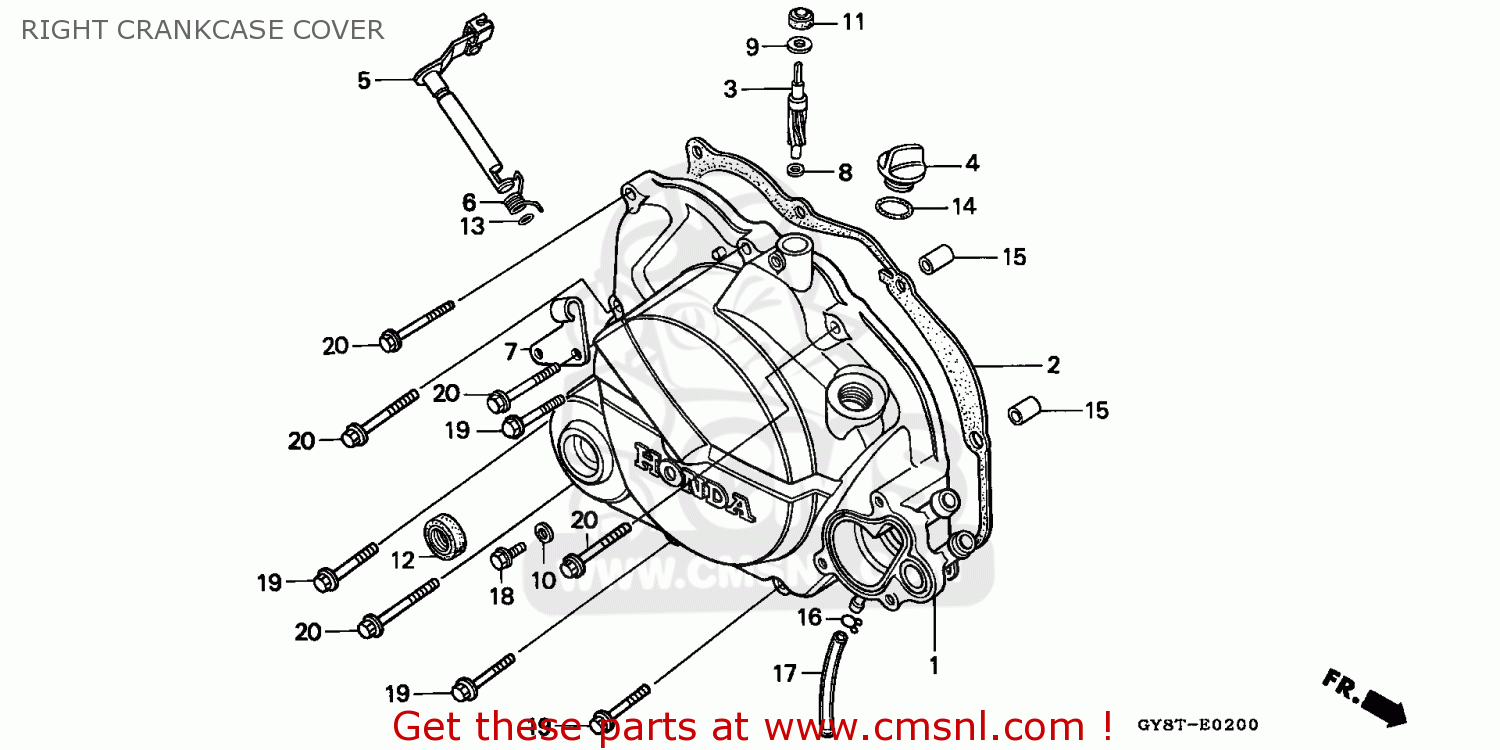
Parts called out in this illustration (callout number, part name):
1	COVER COMP.,R.CRA
2	GASKET,R.CRANKCAS (NAS)
3	GEAR,TACHOMETER
4	CAP, OIL FILTER
5	LEVER COMP.,CLUTC
6	SPRING,CLUTCH LEV
7	RECEIVER,CLUTCH C
8	WASHER A,TACH.
9	WASHER,THRUST 6.7
10	WASHER, 12MM
11	OIL,6.5X14.5X7
12	OIL SEAL,16X28X7
13	O-RING,9MM
14	O RING,16MM
16	CLIP FUEL 3.5MM
17	TUBE,V,4.5X6.5X60
18	BOLT,FLANGE,6X10
19	BOLT,FLANGE,6X28
20	BOLT,FLANGE,6X35
